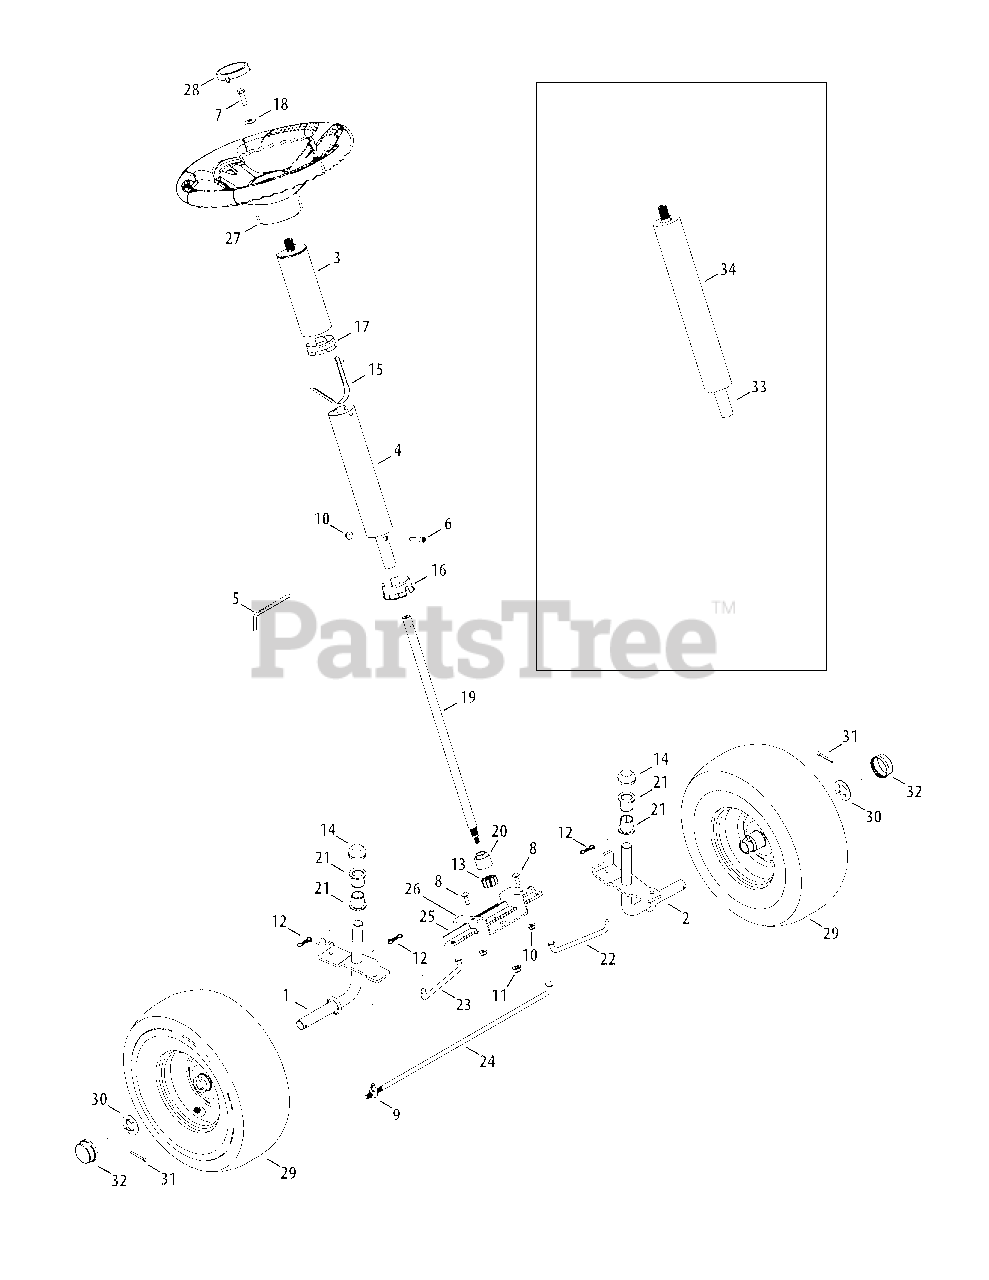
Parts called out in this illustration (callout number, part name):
1	Front Axle Assembly, RH
2	Front Axle Assembly, LH
3	Upper Tube Assembly
4	Lower Tube Assembly
5	Allen Wrench, 3/16
6	Screw, 1/4-20 X 1.25
7	Hex Head Screw, 5/16-18:1.00
8	Carriage Screw, 1/4-20, .75
9	Ferrule, 5/16-24 X .312 Dia.
10	Flange Lock Nut, 1/4-20
11	Flange Lock Nut, 3/8-16
12	Bow-Tie Cotter Pin, 72
13	Steering Pinion Gear
14	Push Cap, 3/4
15	Snap Butt
16	Lower Steering Collar
17	Upper Steering Collar
18	Bevel Washer, .340X.872X.060
19	Steering Shaft, .625 OD X 18.03
20	Hex Flange Bearing, 5/8
21	Flange Bearing, .760 X .941 X 1.0
22	Steering Rod, LH
23	Steering Rod, RH
24	Front Tie Rod
25	Steering Rack Plate
26	Lower Steering Bearing
27	Steering Wheel, Std. Grip
28	Sprig Cap
30	Washer, .781 x 1.59
31	Cotter Pin, 5/32 x 1.25
32	Hub Cap
34	Steering Sleeve
